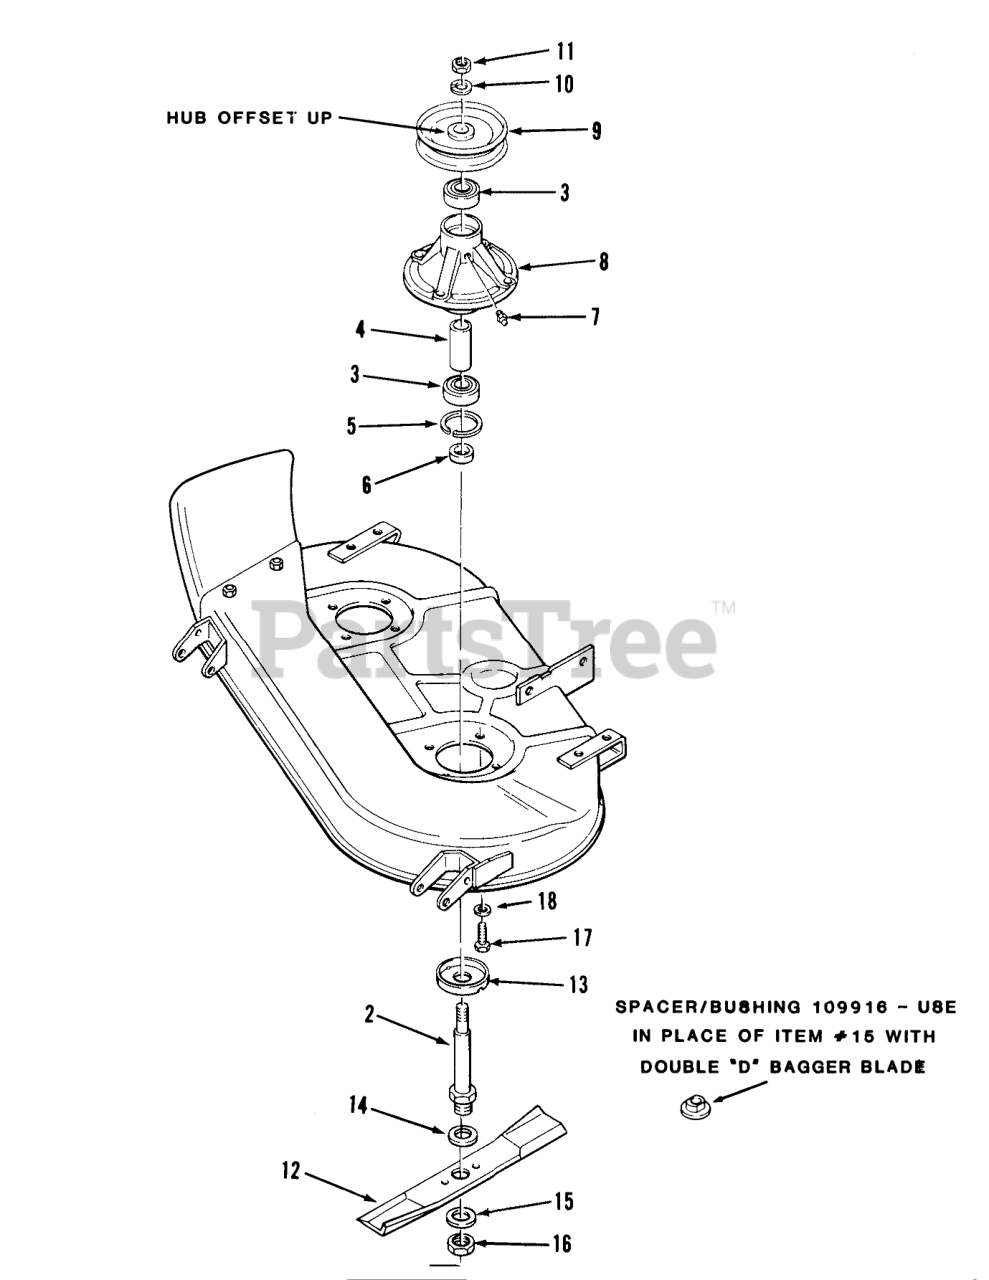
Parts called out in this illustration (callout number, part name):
2	SHAFT SPINDLE
3	BEARING-BALL
5	Ring-Snap
6	SPACER-BLADE
7	Fitting-Grease
8	HOUSING SPINDLE
9	BLADE PULLEY
10	Lockwasher
11	Jam Nut
12	ASSY BLADE KIT
13	CUP-SPINDLE
14	Washer
15	Washer
16	Nut-Jam
17	BOLT
18	LOCKWASHER
